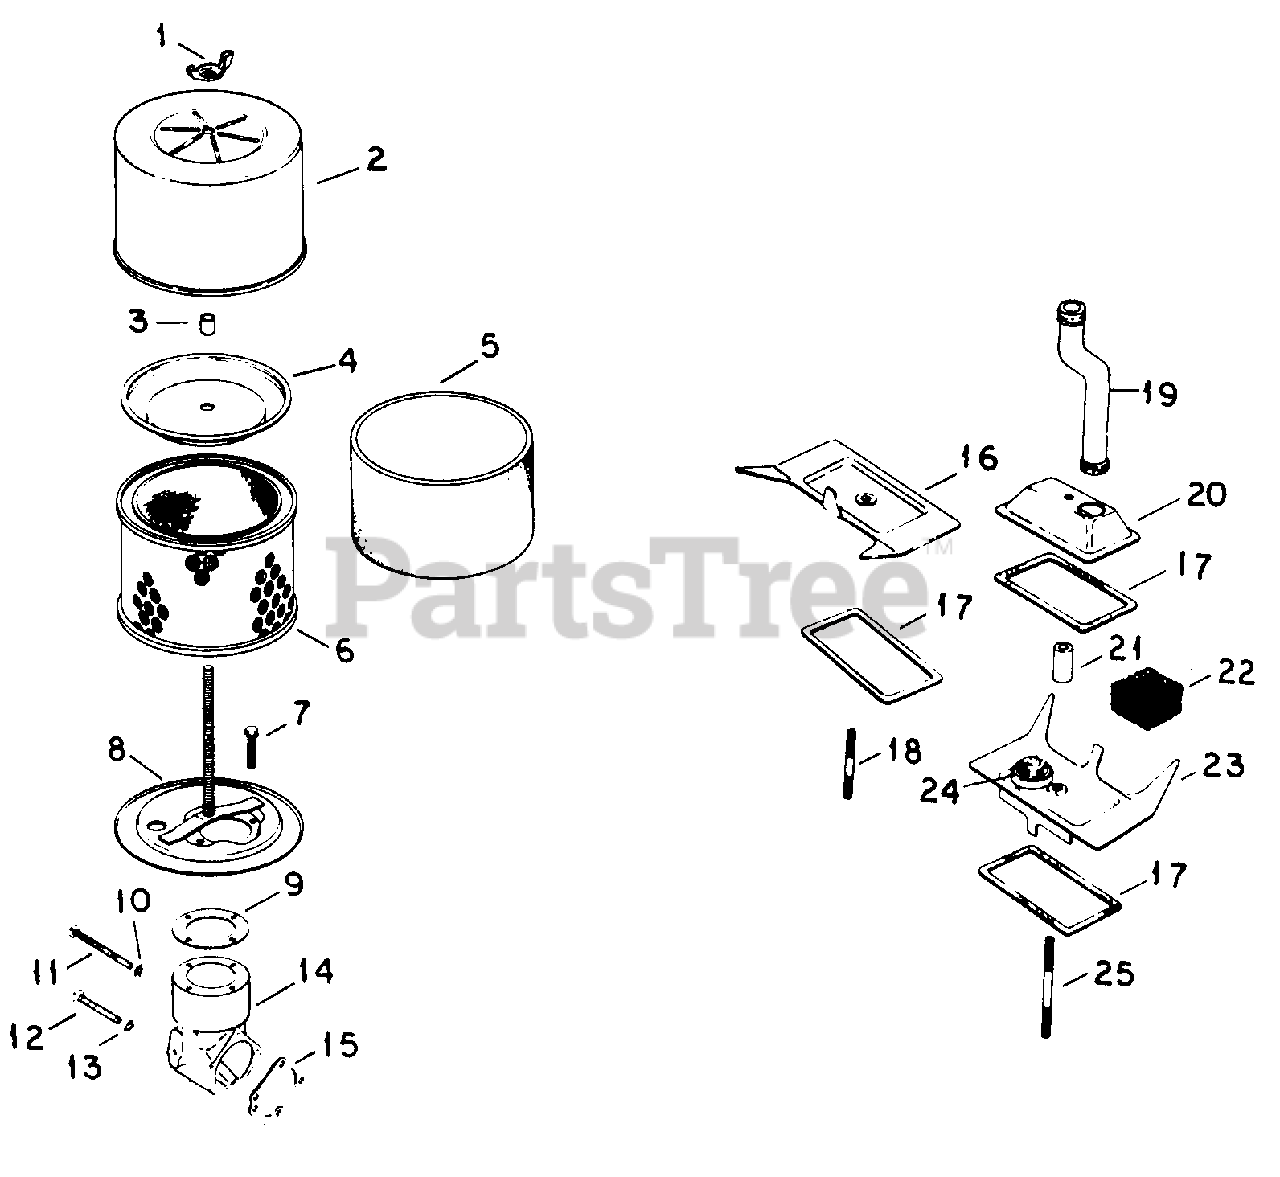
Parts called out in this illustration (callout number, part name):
1	Nut, Wing, 1/4-20
2	Cover, Air Cleaner
4	Cover, Air Cleaner Element
5	Element, Precleaner
6	Element, Air Cleaner
7	Screw, No. 10NF X 1/2 H/Whd Tap
8	Base, Air Cleaner
9	Gasket, Air Cleaner Base
10	Washer, .188 X .438 X .036
11	Screw, 10-32 X 2-1/4 Slt Pn Hd
12	Screw, 10-32 X 1-1/2 Slt Pn Hd
13	Washer, No. 10 Int Tooth Lock
14	Elbow, Air Intake
15	Gasket, Elbow
16	Cover, Valve
17	Gasket, Cover
18	Stud, 1/4-20 X 2-1/4
19	Hose, Breather
20	Cover, Valve
21	Seal, Breather
22	Filter, Breather
23	Kit, Breather
24	Valve, Umbrella
25	Stud, 1/4-20 X 3-1/4
